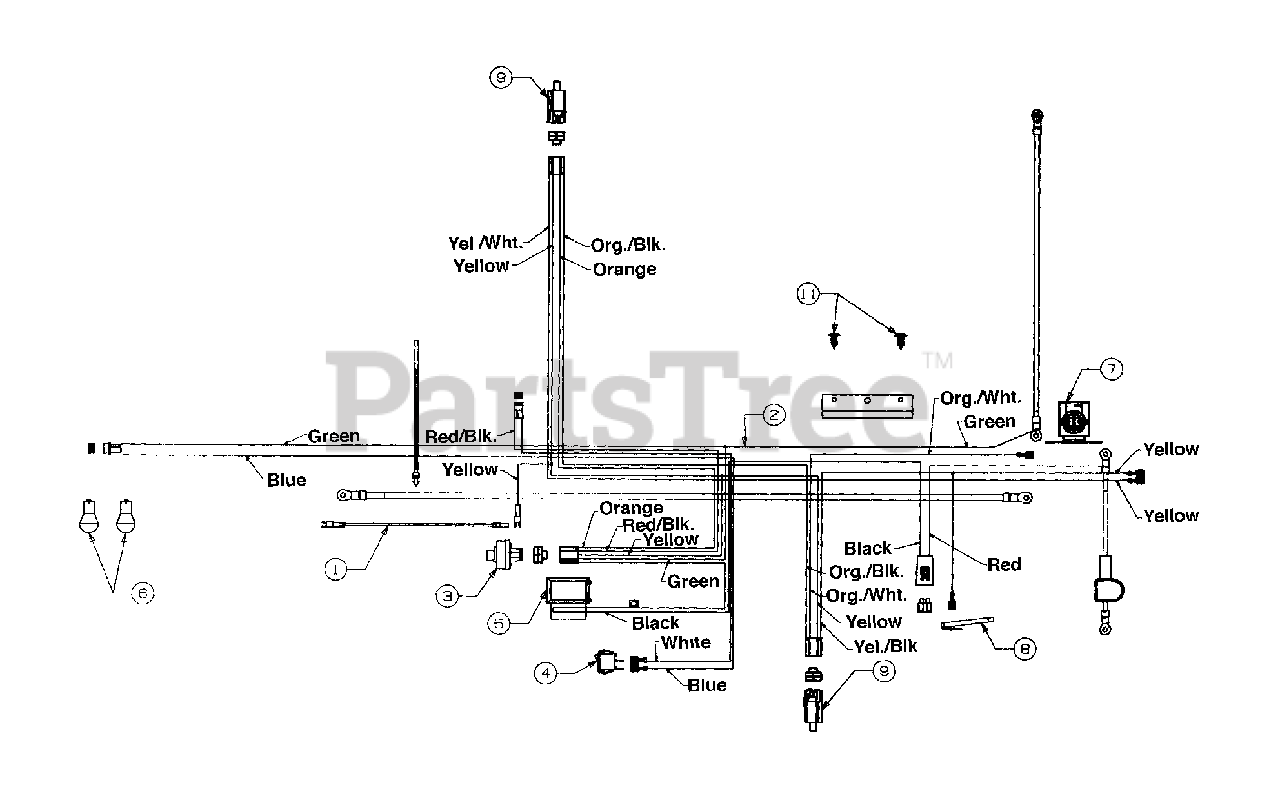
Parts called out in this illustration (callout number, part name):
1	Harness Adapter
2	Wire Harness w/Light Switch and Amp
3	Ignition Switch
4	Light Switch
5	Ammeter
6	Bulb
7	Solenoid
8	Safety Switch
9	Safety Switch
11	Ratchet
